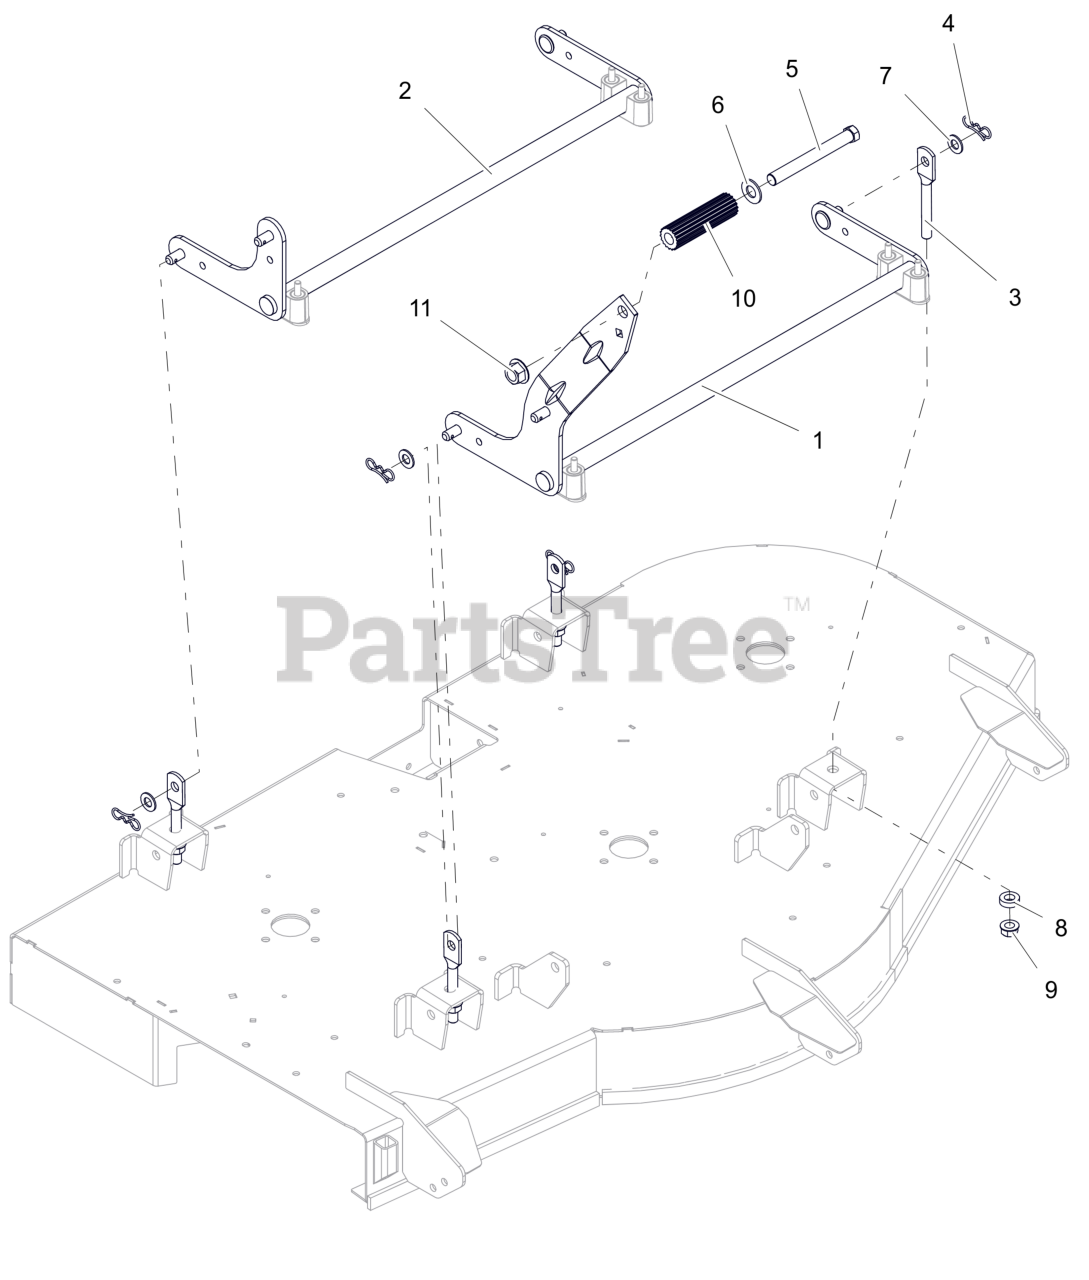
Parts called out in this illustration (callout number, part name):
1	WLDMT- FRONT LIFTPIVOT
2	WLDMT- REAR DECK PIVOT
3	LINK, DECK (HOLE-LONG)
4	PIN, BOWTIE .091X1.875 ZCC
5	BLT, HEX .62-11X5.50 G5 FBP
6	WSHRFLT 5/8SAE CARBHARD FBP
7	WSHR-FL-NYL .518X1.000X.080
8	WSHR, RUBBER
9	NUT-LK-CTR-FLG .500-13 GG ZCC
10	ROD, FOOT PEDAL (BLACK)
11	NUT,FLG-TOP LK .625-11 FBP
